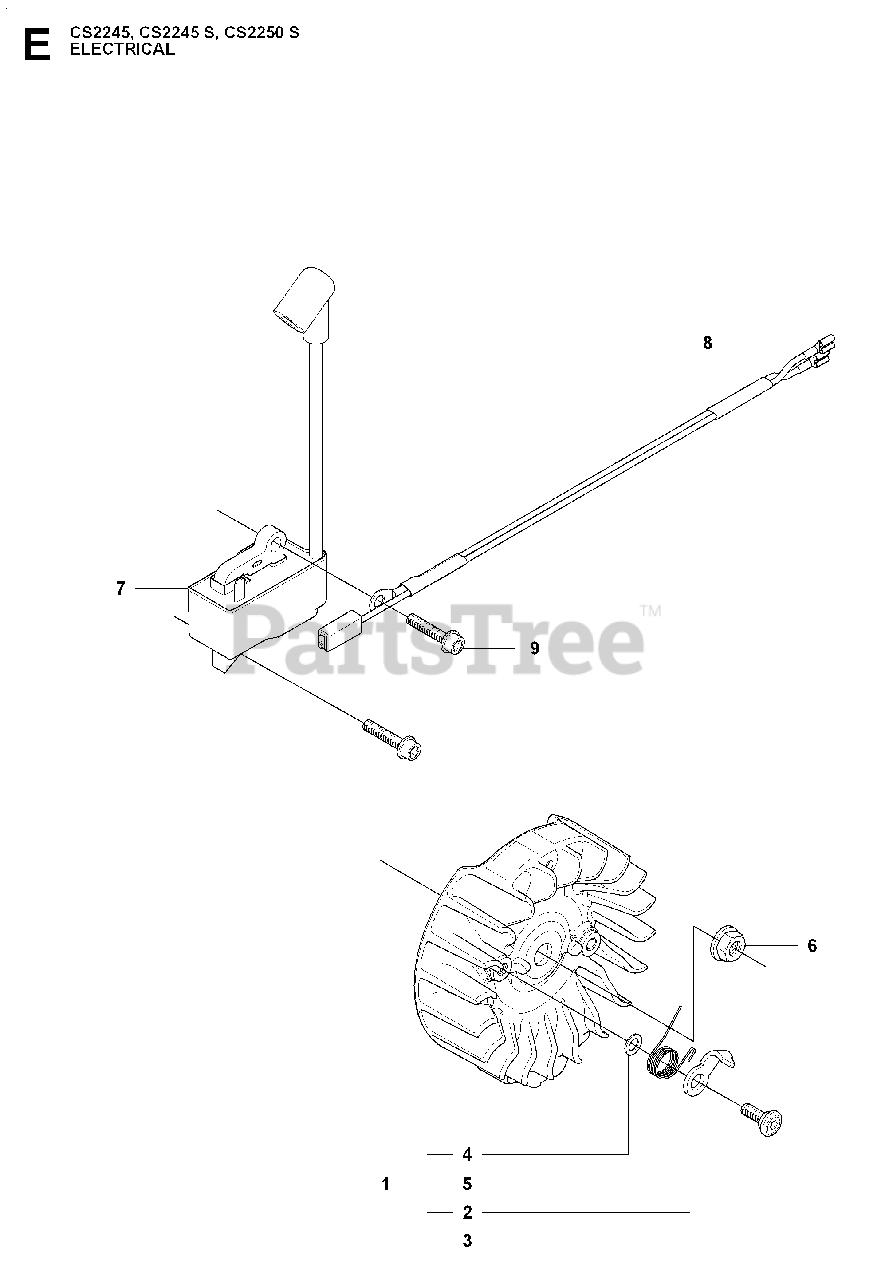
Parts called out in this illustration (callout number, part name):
1	FLYWHEEL ASSY
3	PIN, STARTER CATCH
5	%SPRING, STARTER CATCH
6	NUT W/ WASHER
7	%IGNITION MODULE
8	%WIRING ASSY
